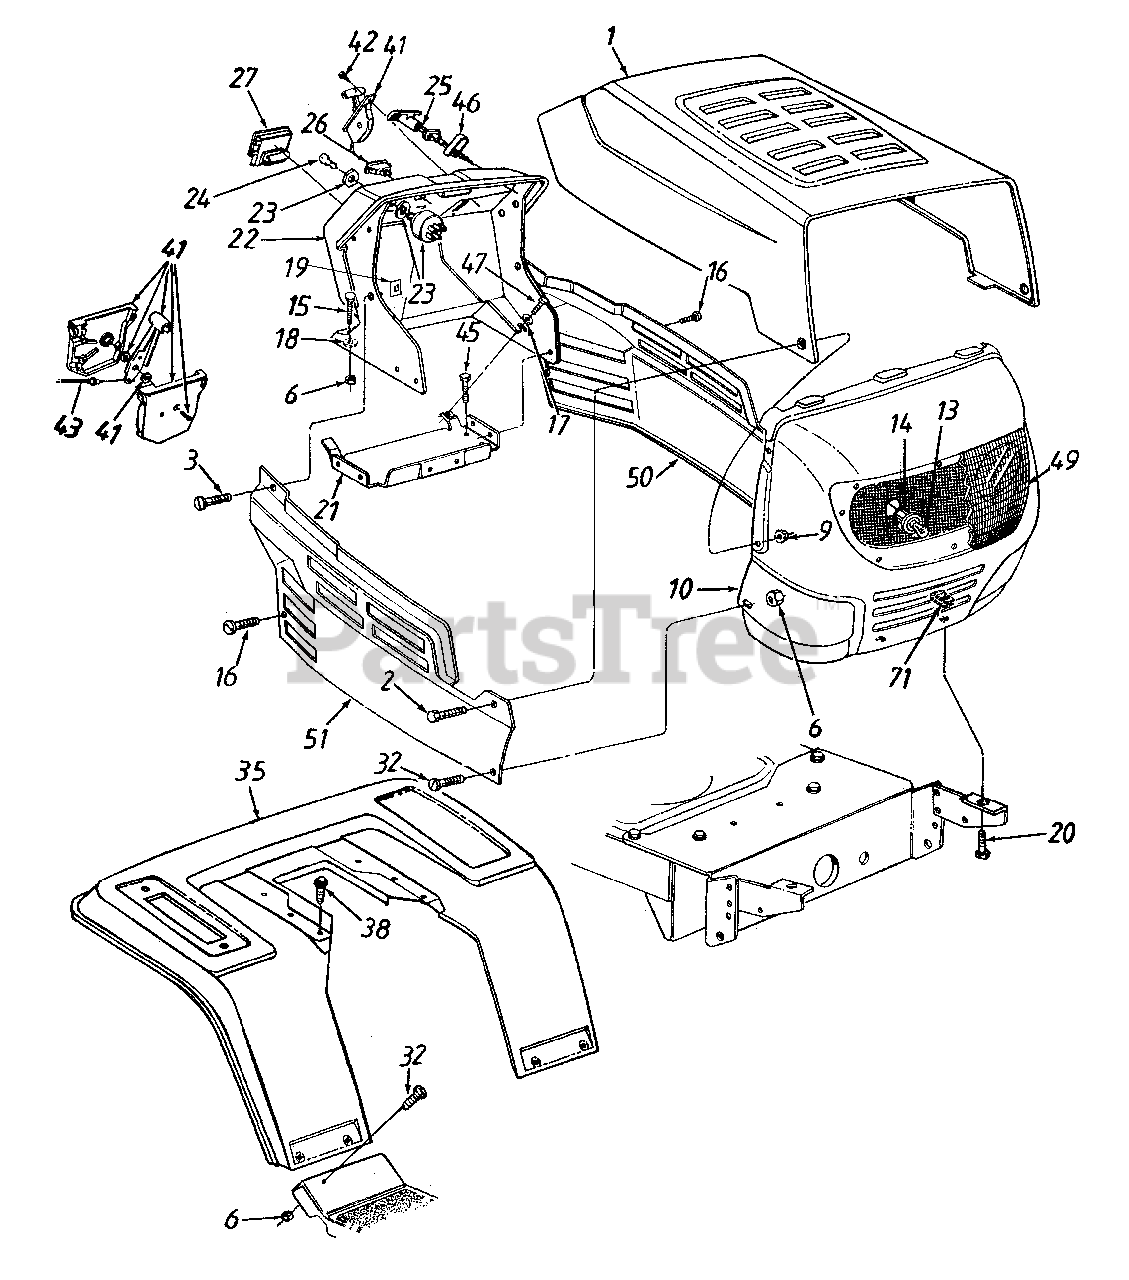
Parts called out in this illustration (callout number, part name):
6	Hex Sems Nut 1/4-20 Thd.
9	Flange L-Nut 1/4-20 Thd.
13	Lamp
14	Socket
15	Carriage Bolt 1/4-20 x .75" Lg.
16	Hex Wash. Hd. TT-Tap Scr.1/4-20 x .5" Lg.
17	Fl-Wash. .281" I.D. x .73" O.D.
18	Bolt Retainer 1/4" I.D.
19	Speed Nut 1/4-20 Thd.
20	Hex Bolt 5/16-18 x .1" Lg. (Gr.5)
23	Ignition Switch
24	Ignition Key
25	Choke Control 23" Lg.
26	Light Switch
27	Ammeter
32	Pan Hd. Scr. 1/4-20 x .75" Lg.
41	Throttle Box Ass'y.
42	Truss Mach. AB-Tap Scr. #10 x .5" Lg.
43	Throttle Control Wire 18.5" Lg.
45	Hex Wash. Hd. B-Tap Scr. 5/16-18 x .5" Lg.
46	Choke Retainer
47	Hex TT-Tap Scr. 1/4-20 x .75" Lg.
49	Lens
